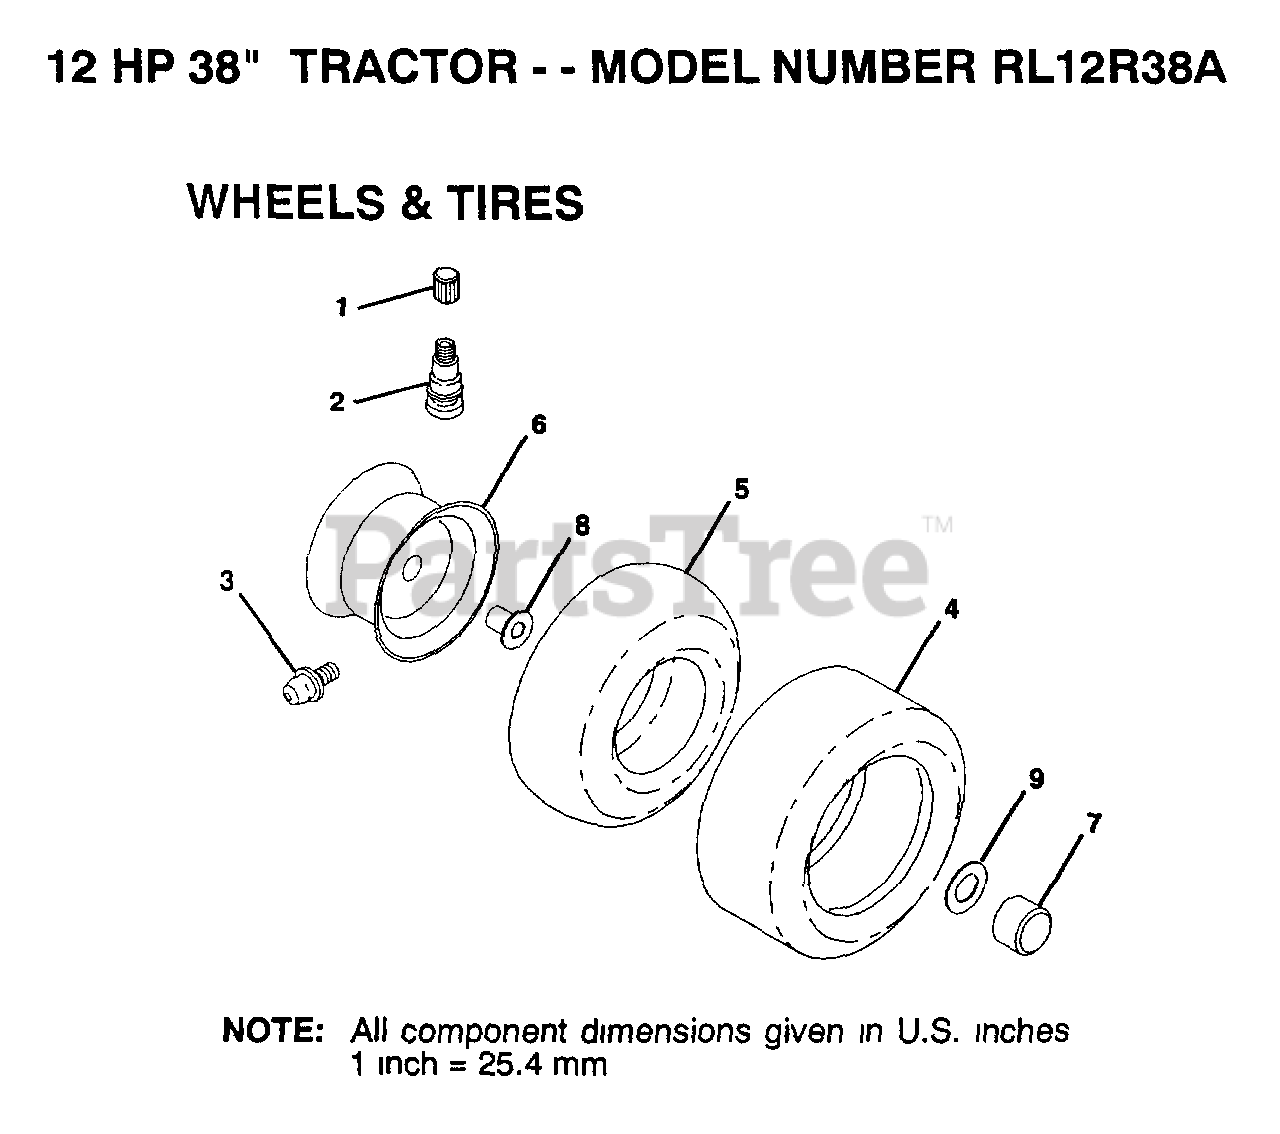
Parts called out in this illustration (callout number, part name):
1	VALVE CAP
2	VALVE STEM LT
3	FITTING LT
5	TUBE.5.3/4.5/6
7	HUB CAP
8	"FLANGE, BEARING"
9	WASHER
